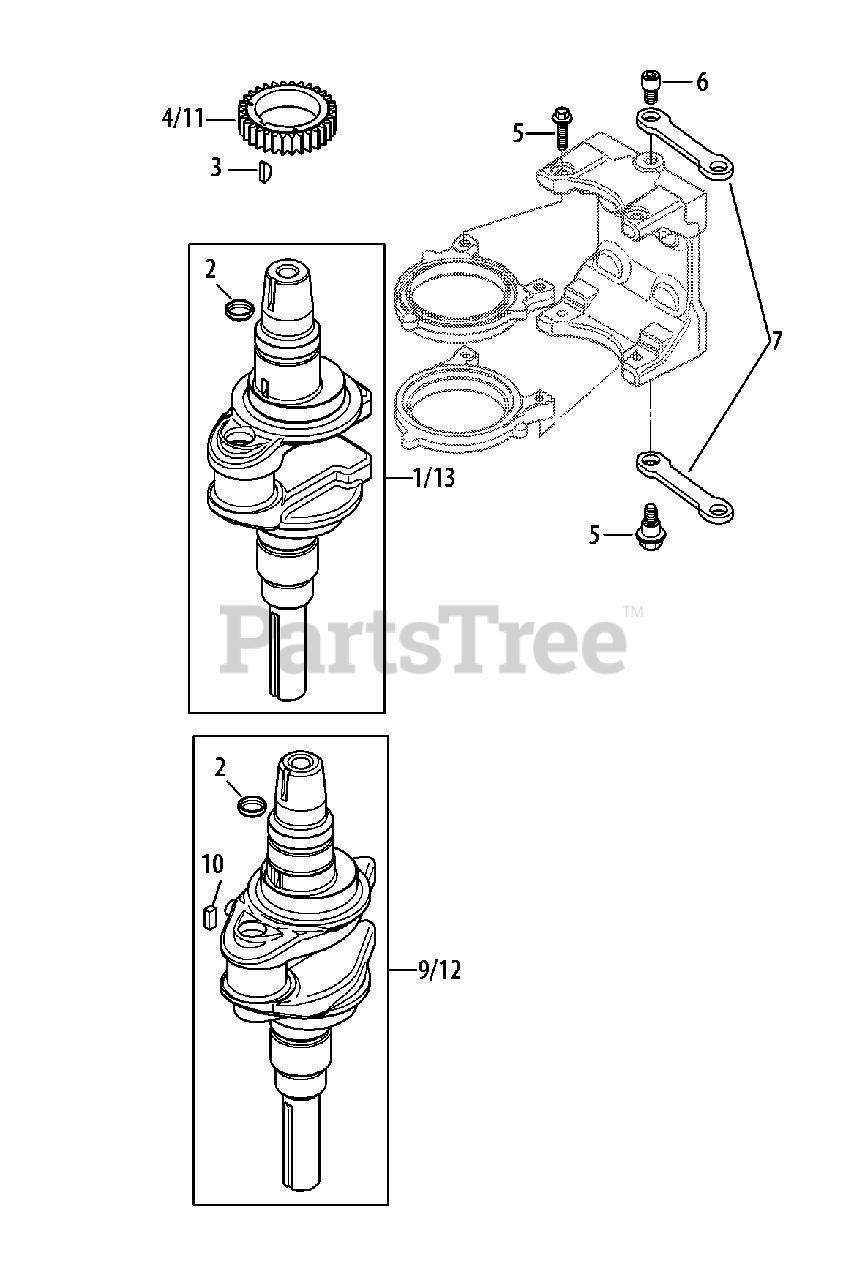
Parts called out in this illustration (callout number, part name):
1	Crankshaft Assembly Kit
3	Key, 3/16 X 5/8
4	Crankshaft Gear
5	Shoulder Screw
6	Link Pivot Screw
7	Balance Weight Linkage
